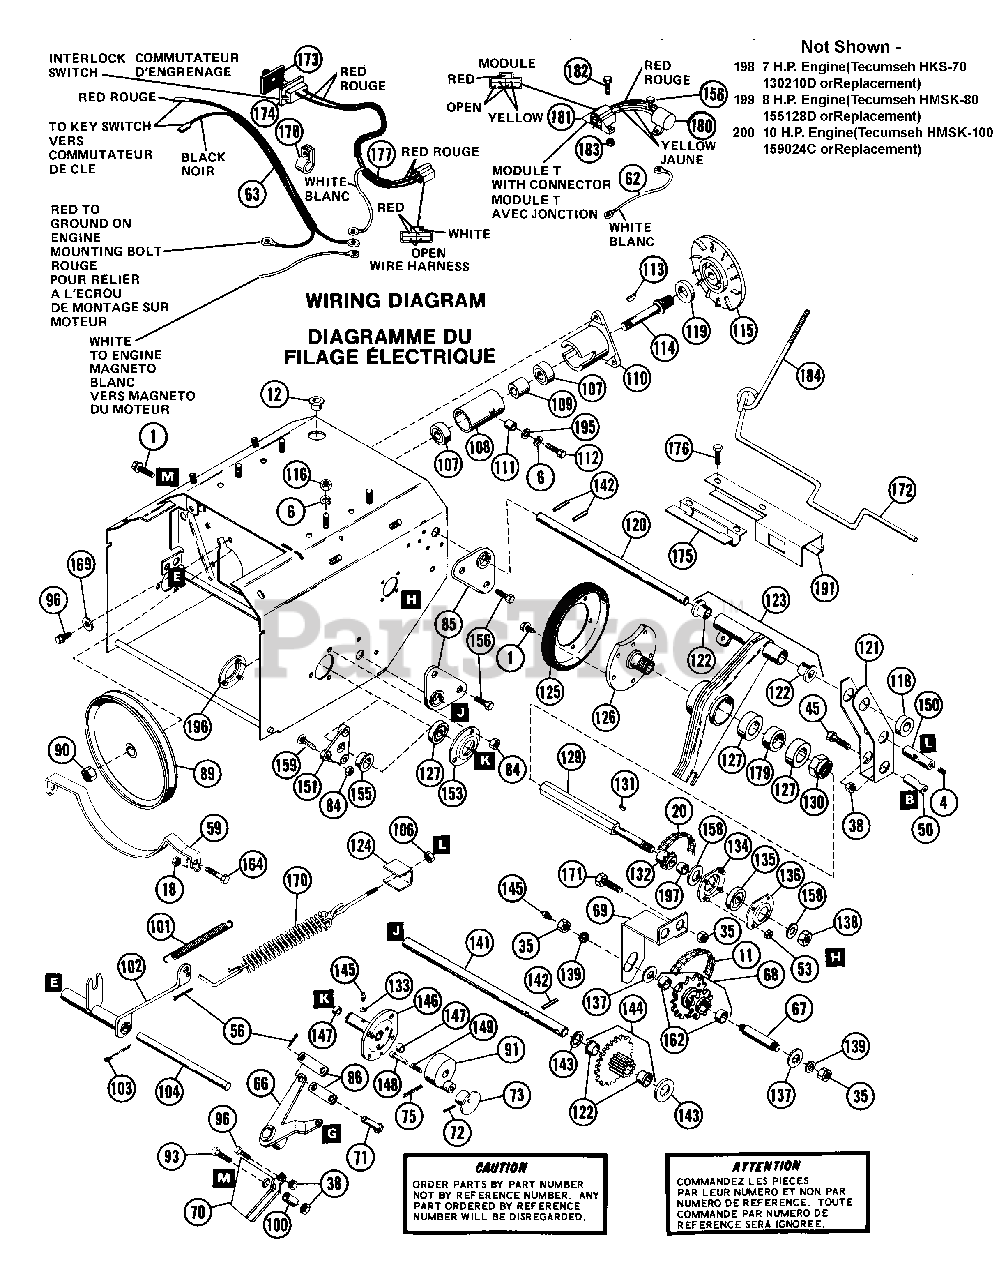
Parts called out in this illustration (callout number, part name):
1	BLT-SERHFWH .31-18X.50 PL
4	SCR-SET .32-18X.38 SKHCUPNL OH
6	WSHR-LK .312X.097 PL HVY
11	PINION CHAIN
12	SNAP BUSHING-.437
18	NUT-LK-CTR .250-20 PL
20	IDLER CHAIN
20	CHAIN
35	NUT-HEX .375-16
38	NUT-LK .312-18 GR A PL
45	BLT-HEX .31-18X.75 PL GR2
50	ROD ADAPTER
53	NUT-LK DUAL FACE 10-24 PL
56	PIN-COTR .09X.75 PL
59	BELT RETAINER
61	BUTTON PLUG 1.0
62	WIRE - GROUND
63	SHORTING WIRE
66	LEVER - SHIFT ARM
67	REDUCTION SHAFT SERVICE ASSEMB
68	SPROCKET ASSEMBLY
69	SUPPORT
69	CLUTCH STOP
70	BRACKET SHIFT LEVER
71	CLEVIS PIN
72	PIN-ROLL .093X1.00
73	KNOB
75	PIN-GRV .250X1.75 TP C
84	NUT-LK-FLG .250-20 PL
85	SUPPORT, SHAFT
86	SHIFT LINK
89	PLY-V 8.00 X 1.0 W/KEY CLARK
90	NUT-LK-NYL.625-18 PL
91	LOCKOUT HUB
93	BLT-HEX .31-18X3.00 PL GR2
96	BLT-HEX .31-18X.50 PL GR2
100	SPACER .5 X .33 X 2.4
101	SG-TENS .080X.73X3.06 WLD 20
102	FORK, CLUTCH
103	PIN-COTR .09X1.0 PL
104	ROD, FORK PIVOT
106	NUT-LK-NYL.312-18 PL
107	BRG-BALL .625X1.375X.44
108	SPINDLE HOUSING
109	BEARING SPACER
110	DRIVE SPINDLE HOUSING
112	BLT-HEX .31-18X1.00 PL GR 2
113	KEY-WDRF .125X.500X.203 SAE 3
114	SPINDLE
115	DRIVE PLATE
116	NUT-HEX .312-18
118	SPACER 1.00 X .64 X .38
119	DRIVE DISC SPACER 1.3X.76X.19
120	CARRIER SHAFT
121	CLUTCH ENGAGEMENT YOKE
122	BSHG-FLG .625X.750X.500X.875BR
123	DISC CARRIER SERVICE ASSEMBLY
124	ADAPTER SPACER
125	FRICTION DISC
126	FRICTION DISC HUB
127	BRG-BALL .876 X 1.750 X .50
129	HEX SHAFT
130	NUT-LK-NYL .875-14
131	KEY-WDRF .125X.625X.250 SAE5
132	9 TOOTH SPROCKET
133	WSHR-LK .250X.047 LT PL
134	BEARING FLANGE
135	BRG-BALL .500X1.38X.437
136	BEARING FLANGE
137	WSHR-FL-STL .382X.812X.062
138	NUT-LK-CTR .50-20 PL
139	WSHR-LK .375X.130
141	PINION SHAFT
142	PIN-ROLL .156X1.00
143	WSHR-FL-STL .630X1.005X.062 PL
144	PINION AND SPROCKET ASSY.
145	SPIN DRIVE ZERK FITTING
146	L. H. AXLE ASSEM
146	L H AXLE ASSEMBLY
147	BSHG-SLV .562X.625X.625 BRZ
148	PIN
149	SG-COMP .028X.34X1.062 WLD75
150	ADAPTER
151	SUPPORT, BEARING
153	BEARING FLANGE
155	BSHG-FLG.875X1X.625X1.250 BR
155	BSHG-FLG .750X1.000X.625X1.250
156	BLT-SERHFWH .25-20X.50 PL
158	WSHR-FL-STL .505X1.000X.062
159	SCR-SLTR-SERNK .25-20X.62 PL
162	BSHG-SLV .500X.625X.500 BR
164	BLT-HEX .25-20X.50 PL GR2
169	WSHR-LK-INT .313X.030 PL
170	SPRING ASSEMBLY
171	BLT-SERHFWH .25-20X.50 PL
172	SWITCH ACTUATOR
173	SWITCH BOOT
175	ROD RETAINER
176	SCR-TAP 10-24X.375 HWH PL TR
177	WIRING HARNESS
180	MODULE T SERVICE ASSEMBLY
181	CONNECTOR
182	BLT-HEX 10-24X.38 PL GR2
183	NUT-KEPS 10-24 PL
184	LOWER ROD INTERLOCK
191	SWITCH RETAINER
195	WSHR-FL-STL.344X.688X.065PL
196	BEARING FLANGE
197	ROLLER
198	7 H.P. Engine(Tecumseh HSK-70 130210D orreplacement)
199	8 H.P. Engine(Tecumseh HMSK-80 155128D orreplacement)
200	10 H.P. Engine(Tecumseh HMSK-100 159024C orreplacement)
